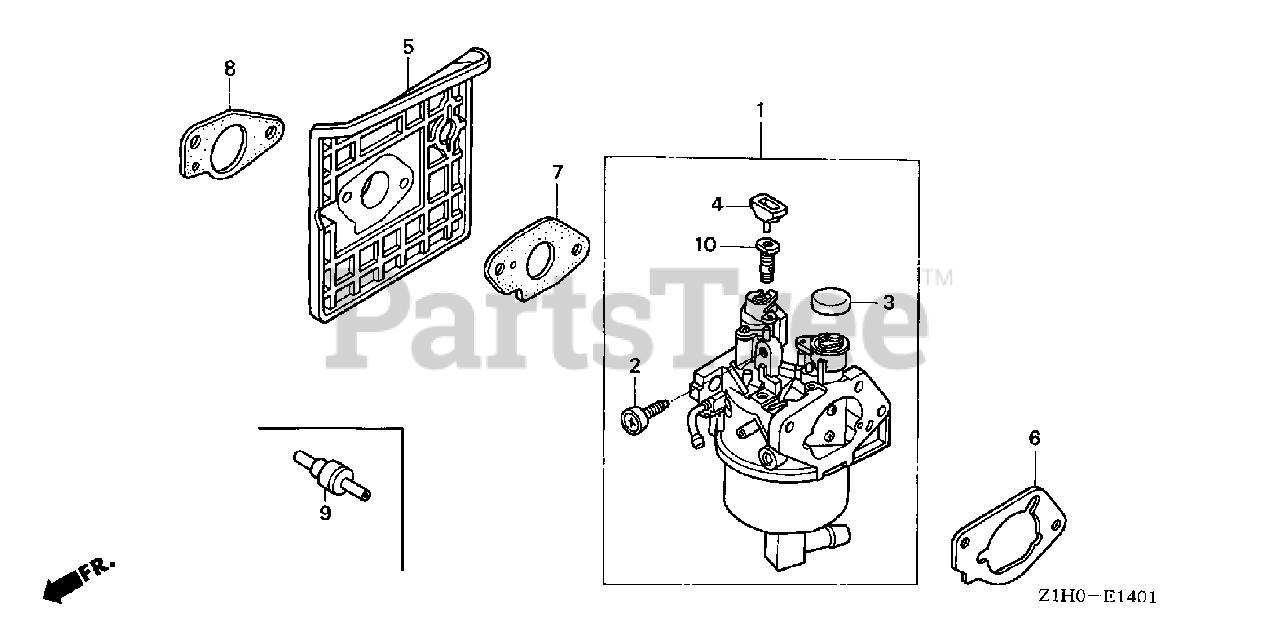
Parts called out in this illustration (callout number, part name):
1	CARBURETOR ASSY. (BEL6A C)
1	CARBURETOR ASSY. (BEL6A D)
2	SCREW, THROTTLE STOP
3	CAP, CHOKE DUST
4	COLLAR, SETTING
5	INSULATOR, CARBURETOR
6	SPACER, CARBURETOR
7	GASKET, CARBURETOR
8	GASKET, INSULATOR
9	VALVE, DASHPOT CHECK
10	JET, PILOT (#45)
